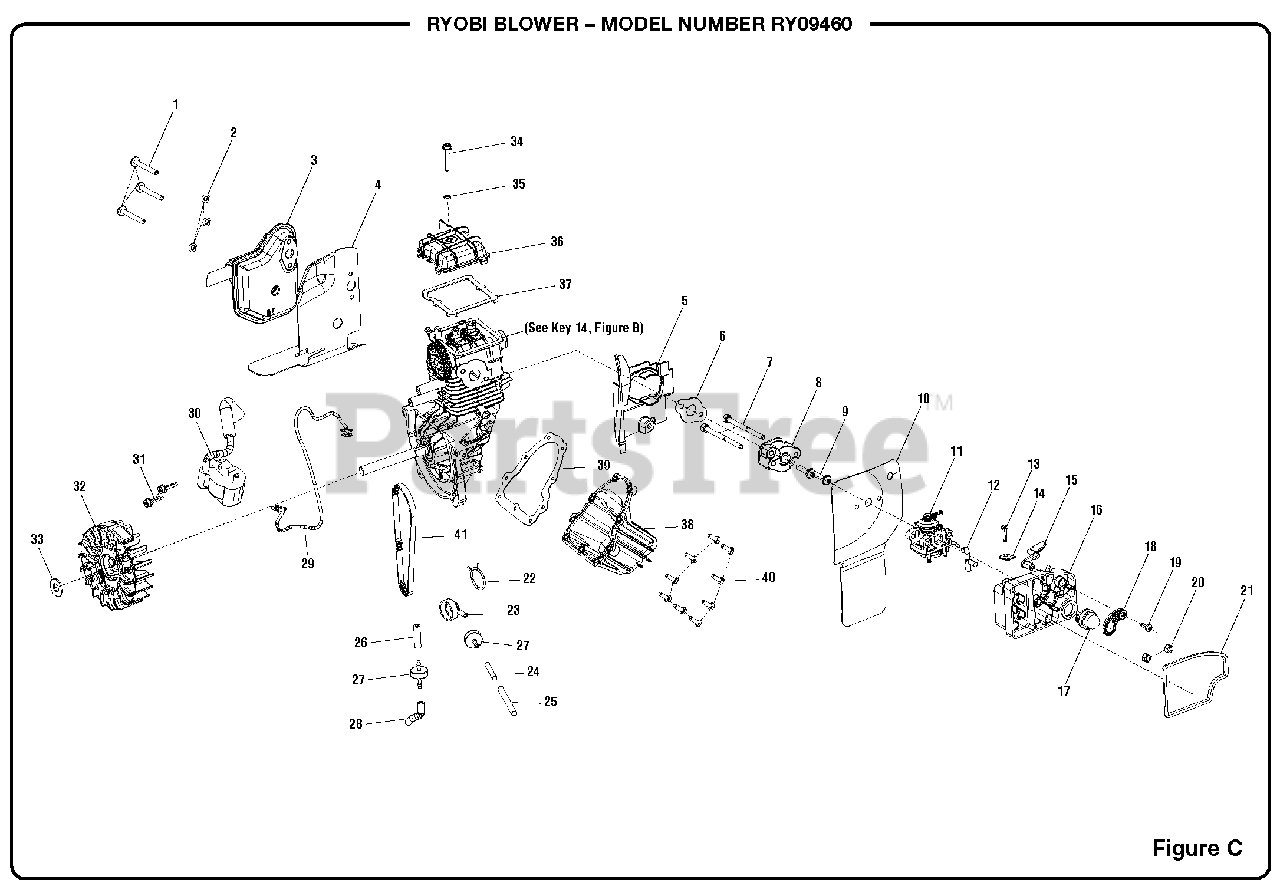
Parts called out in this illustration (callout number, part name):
1	Screw (M5 x 42 mm)
2	Lock Washer (M5)
4	Muffler Gasket
5	Air Baffle
7	Bolt (M5 x 63 mm)
9	Screw (M5 x 23 mm)
11	Carburetor
12	Tubing (90 mm)
13	Screw (M4 x 16 mm)
15	Choke Lever
16	Air Box Base
18	Choke Plate
19	Screw (M4 x 12 mm)
20	Lock Nut (M5)
21	Air Box Seal
23	Breather Fitting
24	Tubing (70 mm)
25	Shield Sleeve
26	Tubing (42 mm)
27	Check Valve
28	Tubing (25 mm)
29	Lead Assembly
30	Ignition Module
31	Screw (M4 x 19 mm)
32	Flywheel Assembly
33	Washer
34	Screw (M4 x 27 mm)
36	Cam Cover
40	Screw (M4 x 12 mm)
